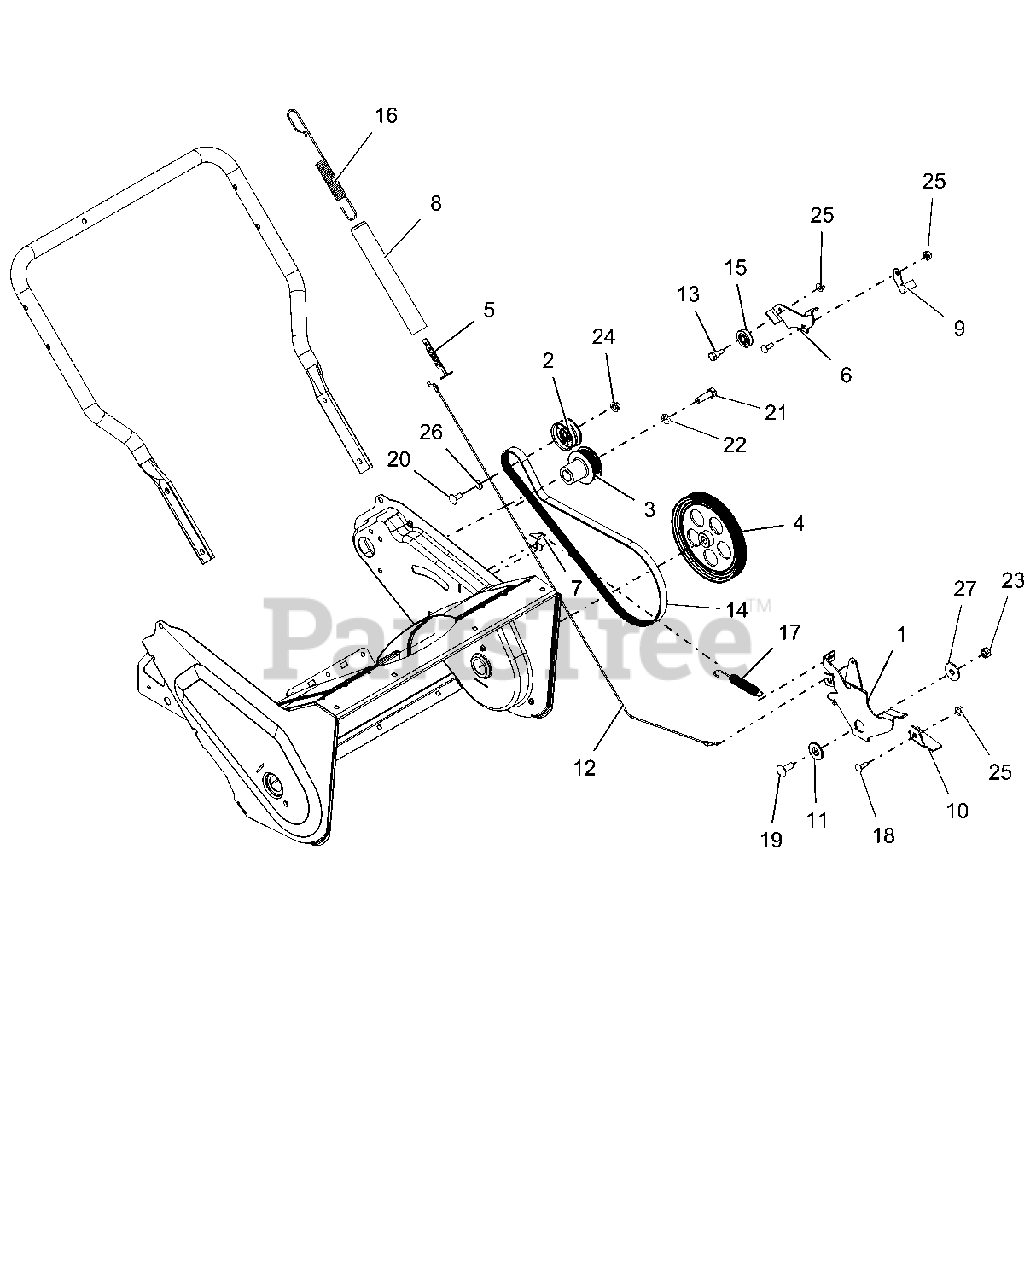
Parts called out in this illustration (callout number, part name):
1	ARM, IDLER/BRAKE
2	IDLER, FLAT - 1.875"
3	SHEAVE, ENGINE - 6J
4	PULLEY, POLY V-BELT J-6 W/HUB
5	PLATE, CABLE ADJUSTMENT
6	BRKT, CABLE PULLEY
7	BRKT, SPRG
8	COVER, CABLE SPRING
9	FINGER, BELT
10	FINGER, BELT
11	BSHG-FLG .555X.860X.220X1.250
12	CABLE, AUGER
13	BOLT, SHLDR-.375X.375X.25-20
14	POLY V-BELT, J-6 RIBS
15	PULLEY, CABLE
16	SPRG, EXT .100X.740X8.175
17	SPRING, EXTENSION-SWIVEL
18	@BLT-RDHDSQNK .25-20X.75 G5YZ
19	@BLT-RDHDSQNK .38-16X1.00 G5YZ
20	@BLT-RHDSSQNK .31-18X.75 G5YZ
21	BLT-HEX .375-24X1.25 GR5 YWZC
22	@WSHR-LK .38X.094 REG YWZC
23	@NUT-LK-CTR .38-16 YWZC
24	@NUT-LK-CTR-FLG .31-18 YZ GR F
25	@NUT-LK-TOP-FLG .25-20 YWZC
26	WSHR-FL-STL .323X.625X.062 YWZ
27	@WSHR-FL-STL .406X1.25X.10 ZC
